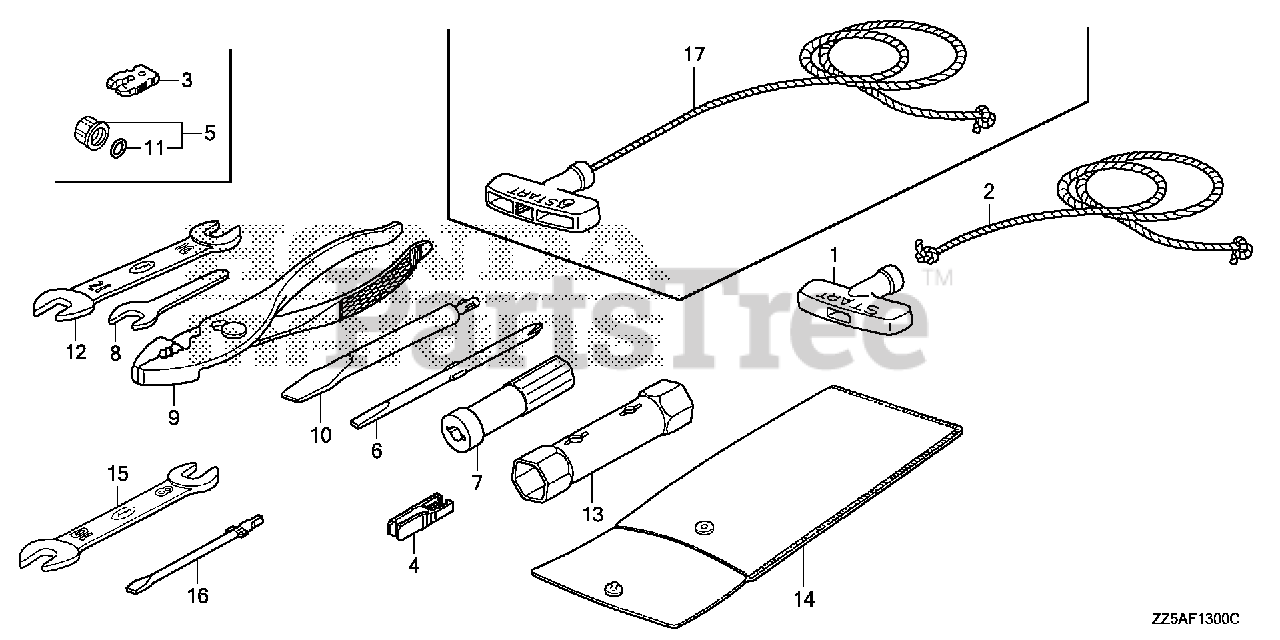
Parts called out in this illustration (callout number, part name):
3	CLIP, EMERGENCY LOCK
4	PULLER, MINI FUSE (SUMITOMO)
7	GRIP, SCREW DRIVER
13	WRENCH, BOX (P18X19)
14	BAG, TOOL (160MM)
15	SPANNER (8X10)
16	DRIVER 3, MINUS SCREW (NO.2)
17	ROPE, STARTER (1600MM)
